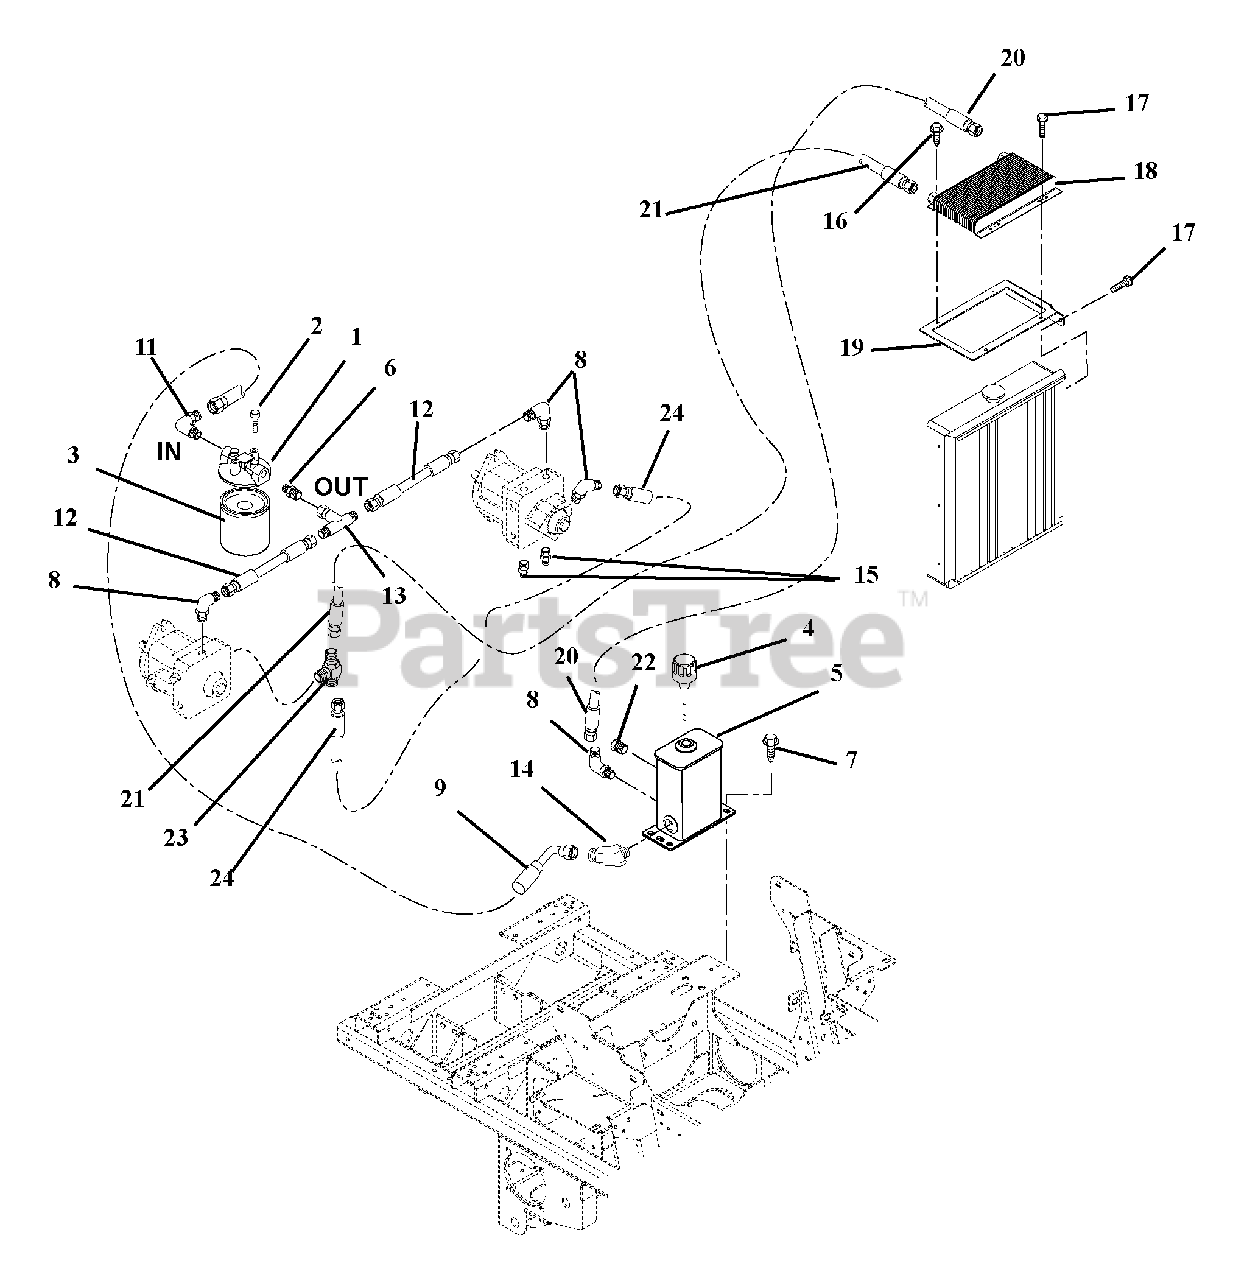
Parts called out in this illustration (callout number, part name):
1	Filter Housing
2	Bolt-Hex .25-20 x .50 Grade 5 Epoxy
3	Filter Element
4	Breather, Dipstick
5	Body, Hydraulic Tank
6	Fitting, Hydraulic, Straight Steel
7	Screw-Tapping .38-16 x .75 Hex Washer Head
8	Fitting, Hydraulic, 90 Degree Elbow
9	Hose-Hydraulic Valve to Tank
10	Hose, Hydraulic, 10-inch
11	Fitting, Hydraulic, 90 Degree Elbow
12	Hose, Hydraulic .50, 5-Inch
13	Fitting, Hydraulic Tee
14	Fitting, Hydraulic .45 Degree Elbow
15	Fitting, Hydraulic (4 F5OLO)
16	Screw-Tapping .25-20 x .50 Hex Washer Head Thread
17	Bolt-Hex .25-20 .50 Grade 5
18	Cooler, Oil Long MFG# 703
19	Bracket, Diesel Oil Cooler Mounting
20	Hose, Hydraulic .50-61-OK F08F0-F08F0
21	Hose, Hydraulic .50-48-0K M08NO-F08FO
22	Plug, Hex, .75-16 O-Ring
23	Fitting, Hydraulic Tee M8O-M8O-M8O 8 S5OLO-Steel
24	Hose, Hydraulic .50-21-OK F08F0-F08F0
